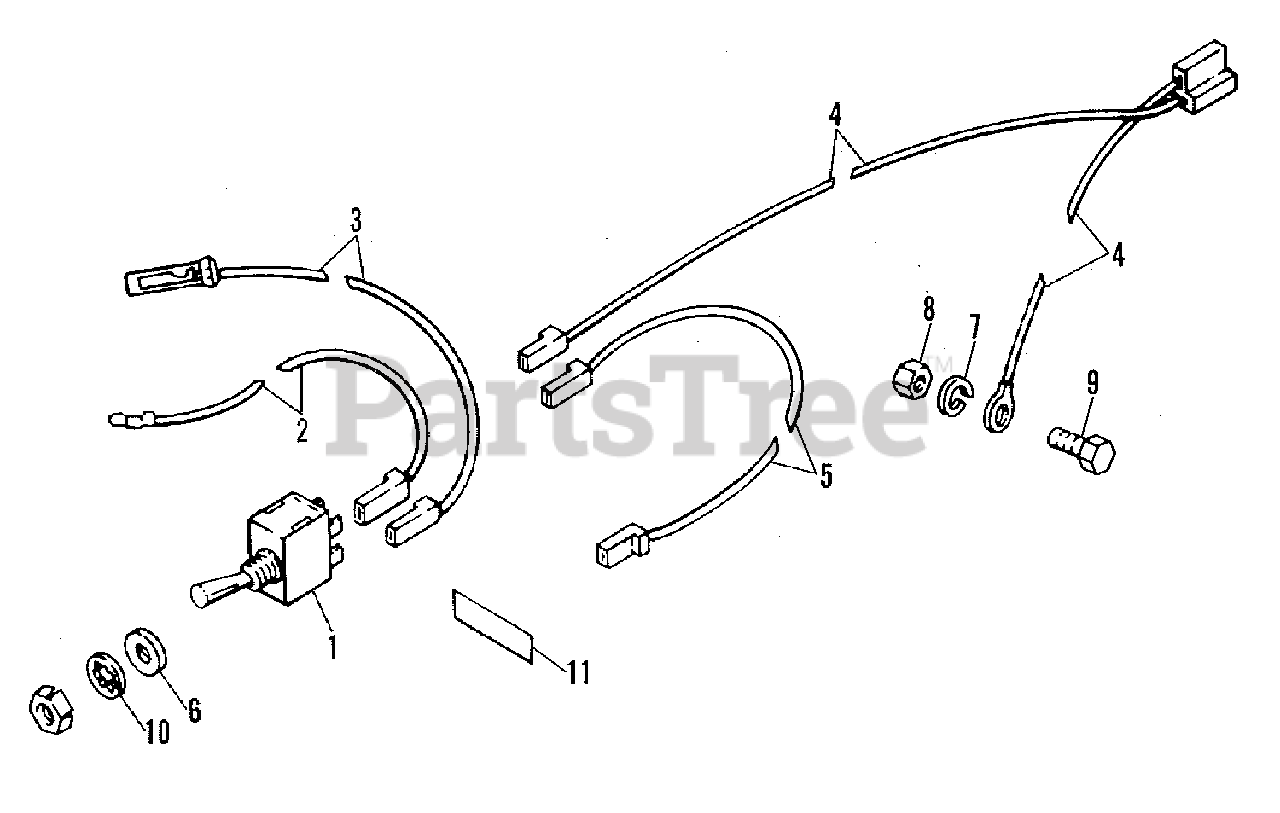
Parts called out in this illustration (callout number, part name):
2	WIRE, Safety (Green)
3	WIRE, Safety (Blue)
4	WIRE ASSEMBLY, Clutch (Black)
5	WIRE ASSEMBLY, Power (Yellow)
7	LOCKWASHER, 1/4
9	CAPSCREW, 1/4NC x 3/4
10	LCOKWASHER, Internal Tooth, 1/2
11	DECAL, Clutch (Located on Dash)
